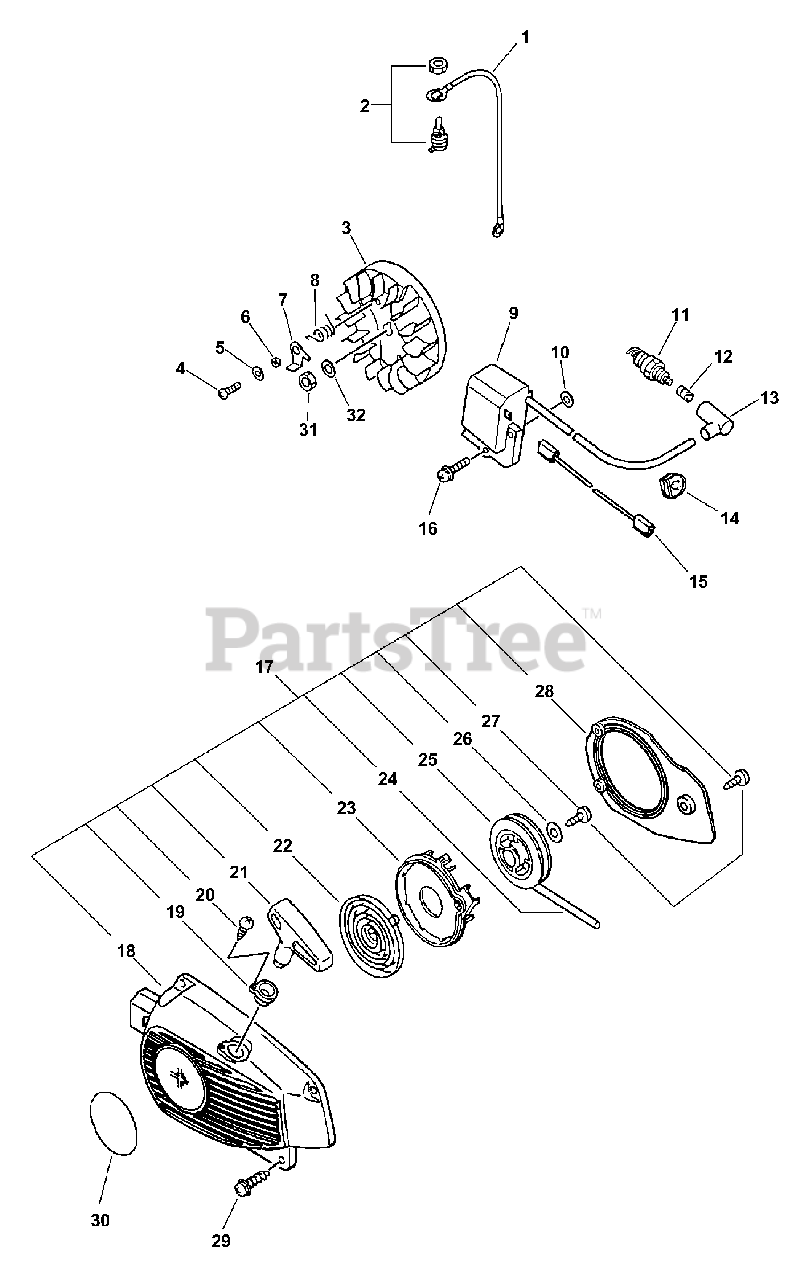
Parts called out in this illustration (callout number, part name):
1	LEAD - GROUND
2	IGNITION SWITCH KIT
3	FLYWHEEL
4	SCREW - 5X12
5	WASHER - 5
7	PAWL, STARTER
8	SPRING, RETURN
9	COIL, IGNITION
11	SPARK PLUG -- BPM-8Y
11	SPARK PLUG -- BPMR-8Y
12	TERMINAL, SPARK PLUG CAP
13	CAP, SPARK PLUG
15	LEAD - IGNITION
16	SCREW - 5X22
17	STARTER ASSY
18	CASE, STARTER - GRAY
19	GUIDE, ROPE
20	SCREW - 3X14
21	GRIP, STARTER
22	REWIND SPRING ASSY
23	PLATE, STARTER
24	ROPE, STARTER - 3X850
25	REEL, ROPE
27	SCREW - 4X14
29	SCREW - 4X16
30	LABEL - ECHO
31	NUT - 8
31	NUT - 8 -- FLANGE
32	WASHER - 8
